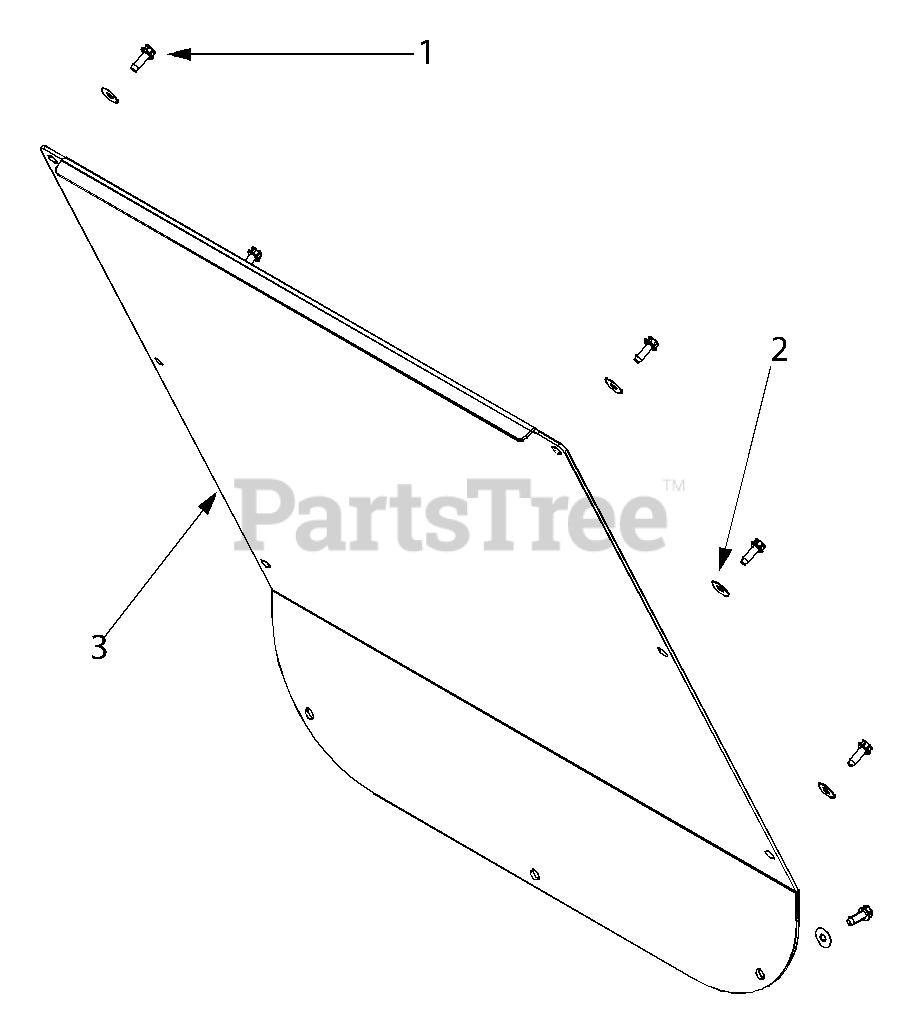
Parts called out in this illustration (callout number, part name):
1	Hex Washer Screw 1/4-20 x .750
2	Flat Washer .283 ID x ..75 OD
3	Windshield Panel
